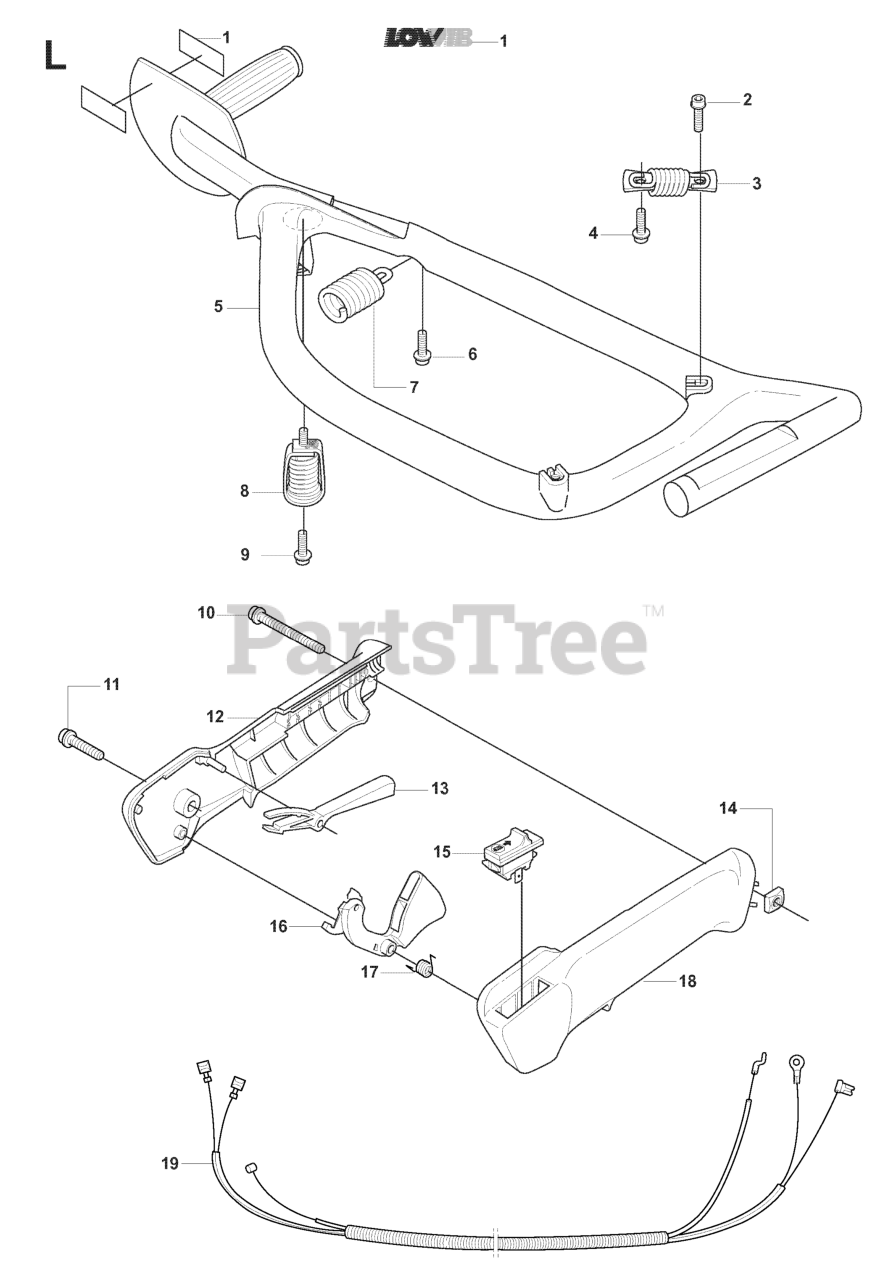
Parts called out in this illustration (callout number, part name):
3	REAR SPRING
8	VIBRATION ABSORBER
9	SCREW
10	SCREW
11	SCREW
13	THROTTLE CATCH
15	STOP BUTTON
16	THROTTLE CONTROL
19	WIRING ASSY HS
